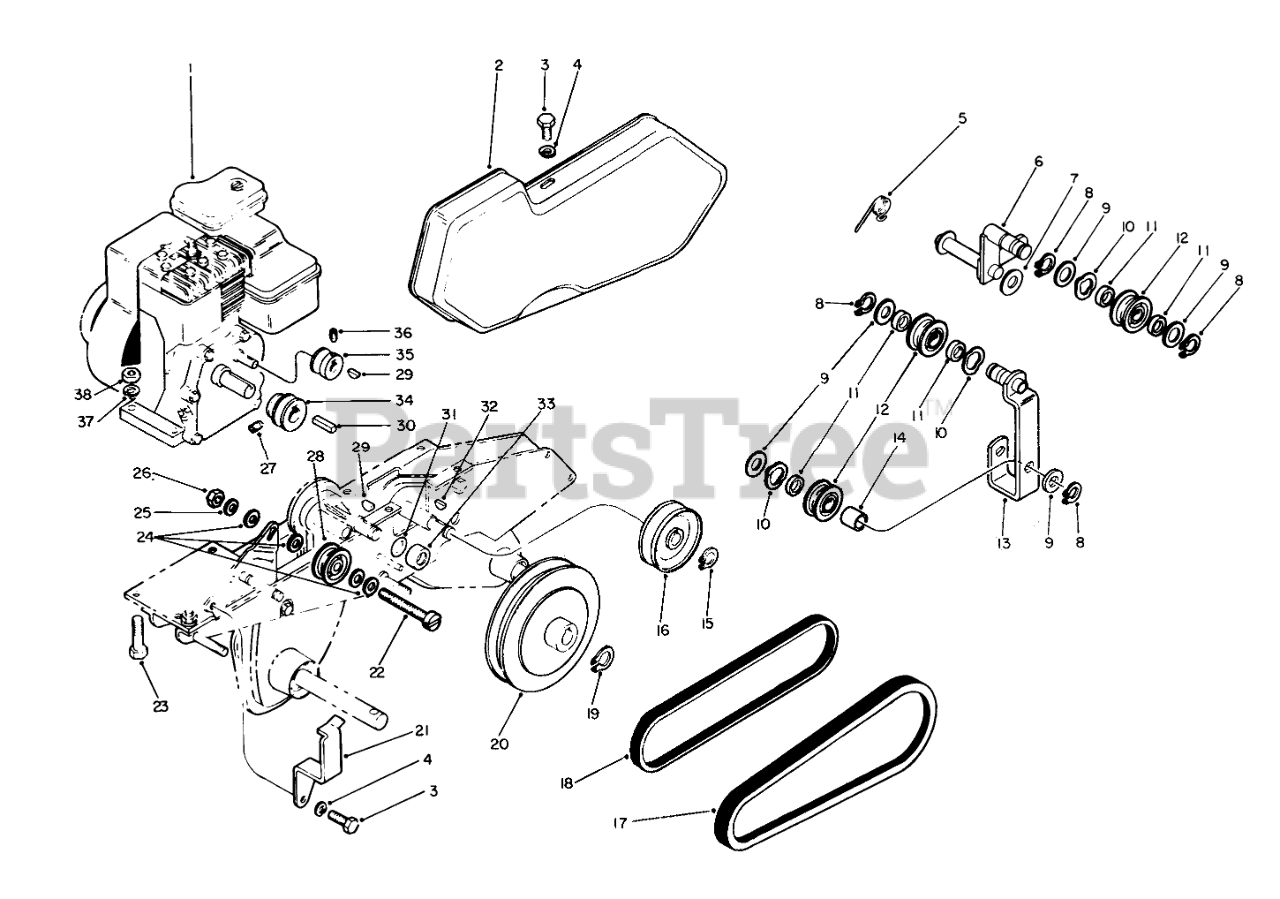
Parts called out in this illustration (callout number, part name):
1	Engine
2	Belt Guard w/Decal
3	SCREW-HH
4	WASHER-LOCK
5	Spring
6	Rocker
7	WASHER-FLAT
8	RING-SNAP, EXTERNAL
9	Washer
10	Wave Washer
11	Spacer
12	Idler Pulley
13	Idler Arm
14	Spacer-Idler
15	Retaining Ring
16	Pulley-Tines
17	Tine Drive Belt
18	Traction Drive Belt
19	Retaining Ring
20	Pulley-Traction
21	Belt Guide
22	Machine Screw
23	SCREW-HH
24	WASHER-FLAT
25	WASHER-LOCK
26	NUT-HEX
27	SCREW-SET, HSH
28	Idler Pulley
29	KEY-WOODRUFF
30	KEY-SQUARE
31	O-Ring
32	KEY-WOODRUFF
33	Seal Cup
34	Engine Pulley
35	Camshaft Pulley
36	SCREW-SET, HSH
37	WASHER-LOCK
38	NUT-HEX
